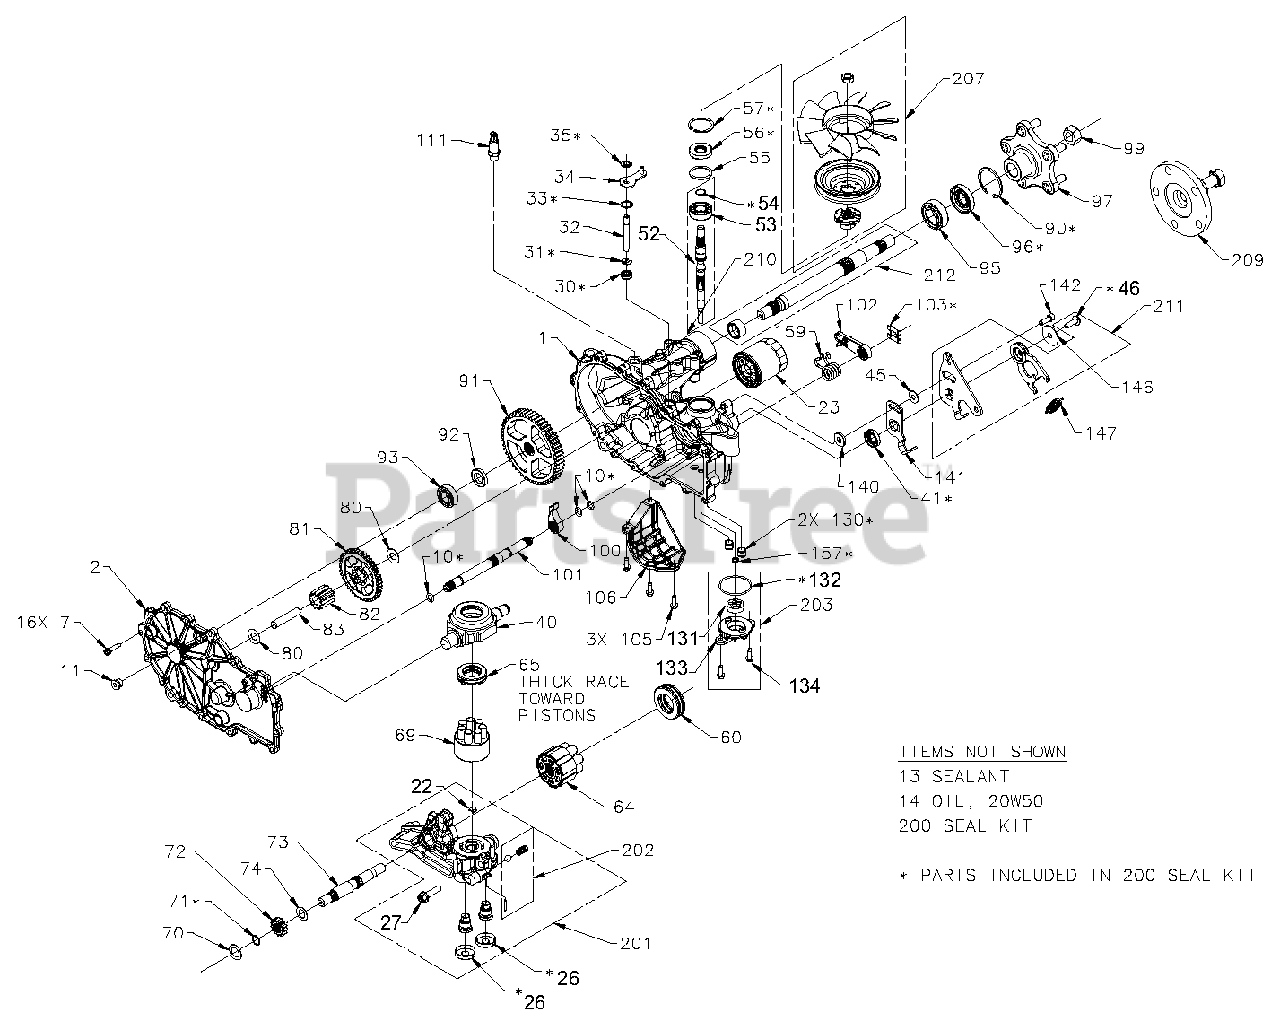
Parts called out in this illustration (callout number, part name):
7	HFHCS 1/4-20 X 1.25
11	PLUG, 9/16-18 (METAL)
22	PLATE, BYPASS
23	FILTER, OIL
30	SEAL, LIP .375 X .75 X .25
31	RING, RETENTION .375 EXTERNAL
33	RING, RETENTION .750 INTERNAL
35	RING, RETENTION .375 EXT
40	TRUNNION, SWASHPLATE
45	WASHER, .34 X .88 X .06
46	TWHCS 5/16-24 X 1.00
53	BEARING, BALL 17 X 40 X 12 OPEN 6203
55	WASHER, 1.23 X 1.56 X .04
56	SEAL, LIP 17 X 40 X 7
57	RING, RET 1.59 INT
65	BEARING, THRUST BALL 30 X 52 X 13
70	WASHER, .63 X 1.0 X .05
71	RING, RETAINING .625
74	WASHER, .72 X 1.16 X .04
80	WASHER, .5 X 1.0 X .03
83	JACK SHAFT
90	RING, RET 2.06 INT
95	BEARING, BALL 1.0 X 52 X 15 OPEN 6205M
96	SEAL, LIP 25 X 52 X 10 TC (GRAY)
99	NUT, HEX LOCK 3/4-16
105	HFHCS 1/4-20 X .75
131	ASSEMBLY, GEROTOR TANG X 1.15 X .39
134	HFHCS 1/4-20 X .75
142	SHCS 5/16-24 X 1 PATCH
146	WASHER, .343 X 1.5 X .062
NS	SEALANT
